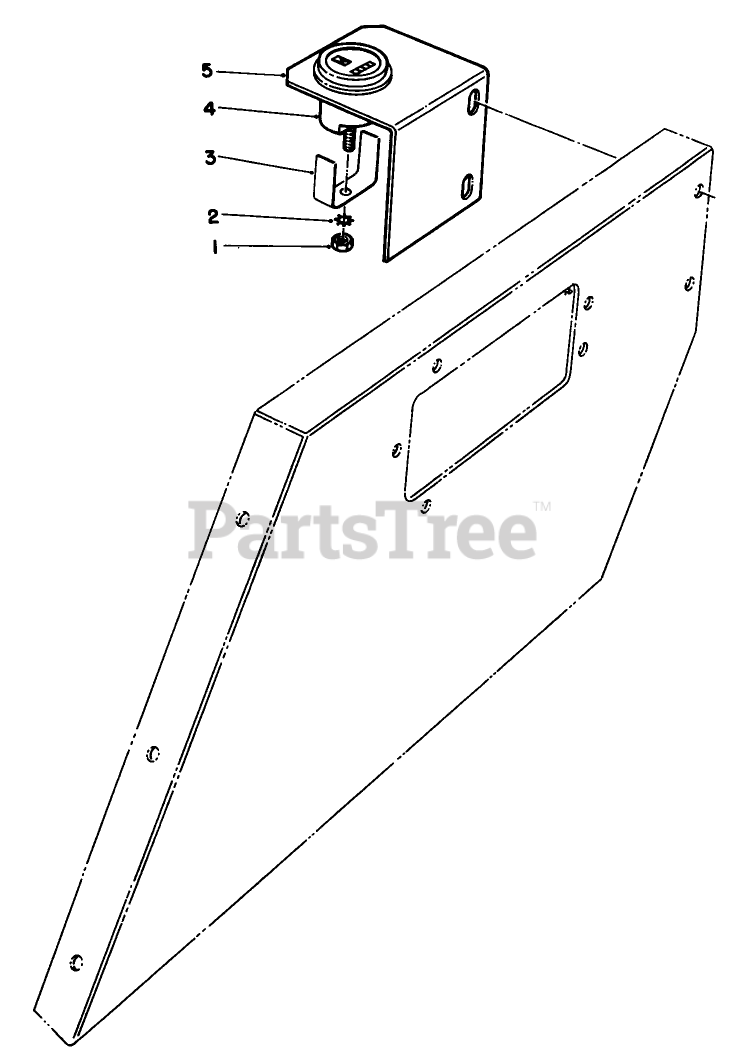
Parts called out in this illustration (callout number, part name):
1	NUT-HEX
2	WASHER-LOCK, INT
3	BRACKET
4	HOUR METER
5	HR.METER BRKT. *R
